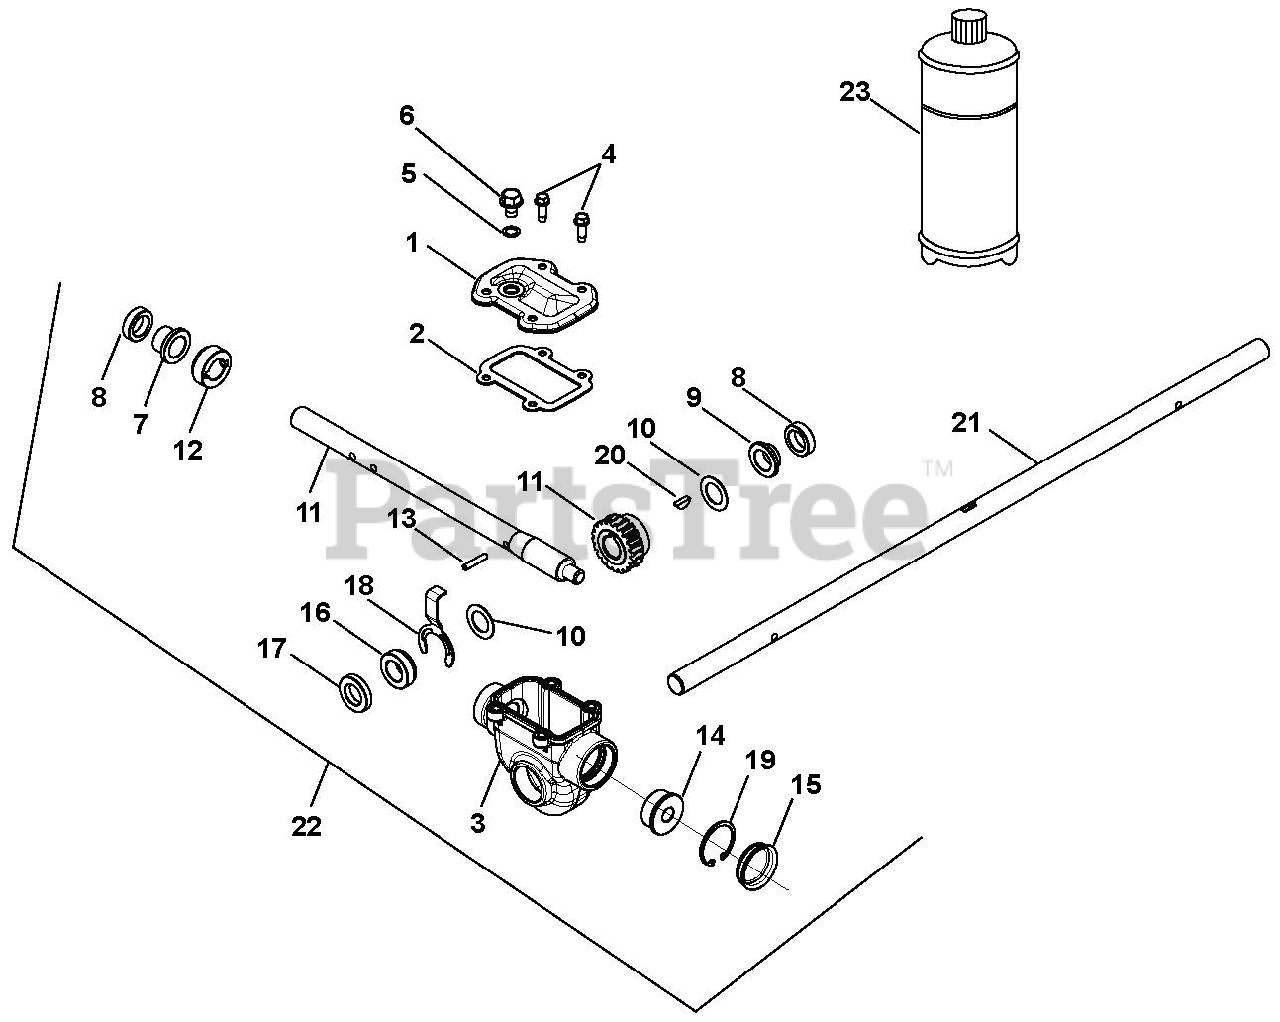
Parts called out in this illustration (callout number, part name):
1	COVER, TOP - COMPACT
2	GASKET, TOP - COMPACT GEARCASE
3	GEARCASE, COMPACT MACHINED
4	BOLT, SEMS .25-20X.50 GR5 YWZC
5	WSHR-BND-SEAL .38X.75X.11 GALV
6	@SCR-ROLOK .38-16X.50 HWH YWZC
7	BSHG-FLG .755X.878X.75X1.25
8	SEAL-OIL .748X1.125X.312 TBC29
9	BSHG-FLG .755X.878X.424X1.25
10	WSHR-FL-STL .760X1.225X.032 YZ
11	SHAFT AND WORM GEAR ASSEMBLY
12	THRUST COLLAR, .75" ID SLIPFIT
13	PIN-STR .188X1.00 6150
14	BSHG-FLG .503X1.303X.62X1.465
15	COVER, GEAR CASE 1.50"
16	BSHG-FLG COMPACT, RIGHT
17	SEAL-OIL .748X1.300X.250 TBC29
18	BUSHING RETAINER, COMPACT
19	RG-RTNG-INT 1.500X.050
20	KEY-WDRF .19X.63 HRD #61
21	SHAFT, RAKE - 20" (.750 DIA)
21	SHAFT, RAKE - 22" (.750 DIA)
21	SHAFT, RAKE - 24" (.750 DIA)
22	GEAR CASE, 20" IRON SM TOP-LD
22	GEAR CASE, 22" IRON SM TOP-LD
22	GEAR CASE, 24" IRON SM TOP-LD
23	ARIENS L3 LUBE, 8 OZ BOTTLE
